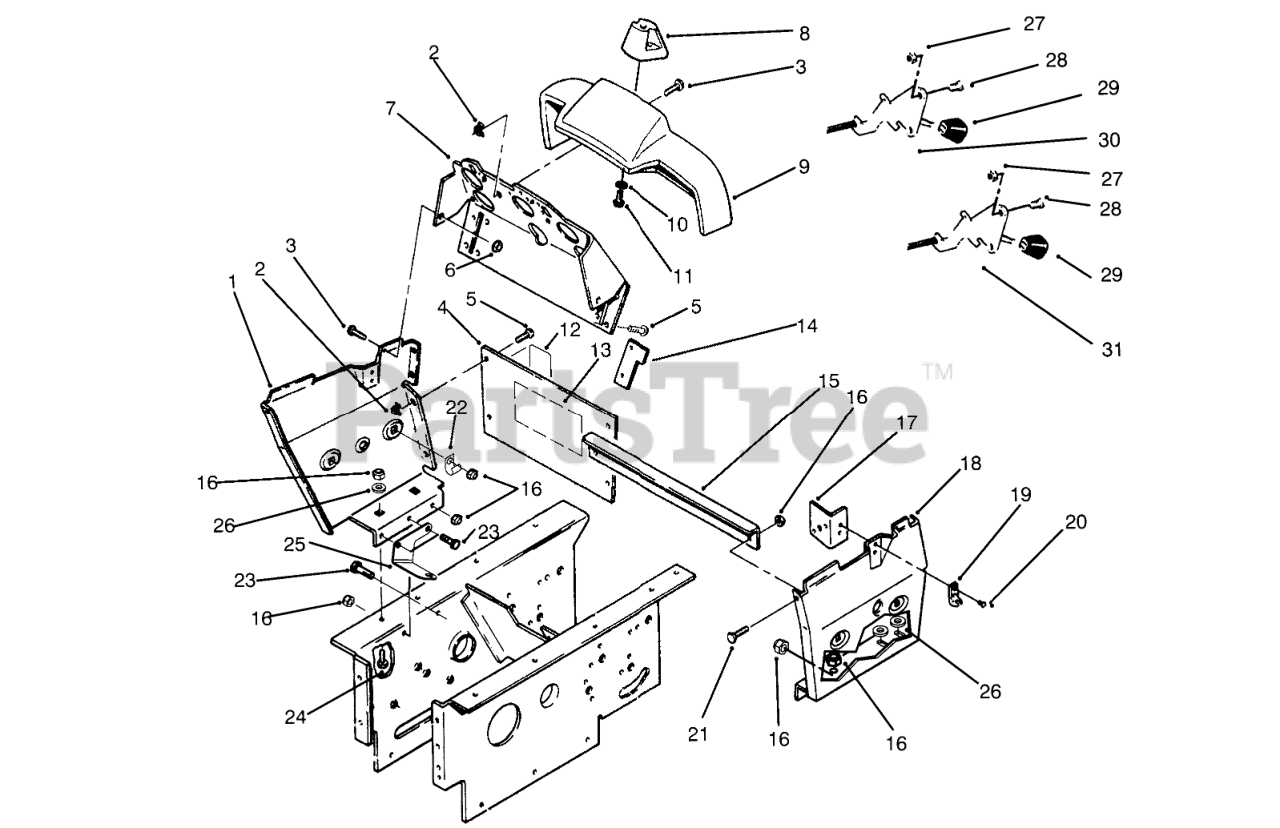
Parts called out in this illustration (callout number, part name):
1	Panel-RH
2	NUT-RETAINED
3	Screw
4	Plate-Hoodstand, Rear (Incl. Ref. #13)
5	Screw
6	NUT-HF
7	ASM-Panel
8	COVER-STEERING SHAFT
9	COVER-CONSOLE 5 GAGE
10	SWIVEL JACK
11	SCREW-#6 PLASTITE
12	DECAL PTO CLUTCH
13	DECAL - DANGER
14	STOP-CHOKE
15	STIFFENER-PANEL B
16	NUT-LOCK, NI
17	BRACKET-SWITCH SU
18	Panel-LH
19	KEEPER-LATCH
20	RIVET-POP
21	SCREW-HH
22	CLIP
23	SCREW-HH
24	CARRIAGE BOLT -4
25	Bracket-Control
26	WASHER-PLAIN
27	Nut
28	SCRW-PHC
30	CONTROL-THROTTLE
31	CONTROL-CHOKE
